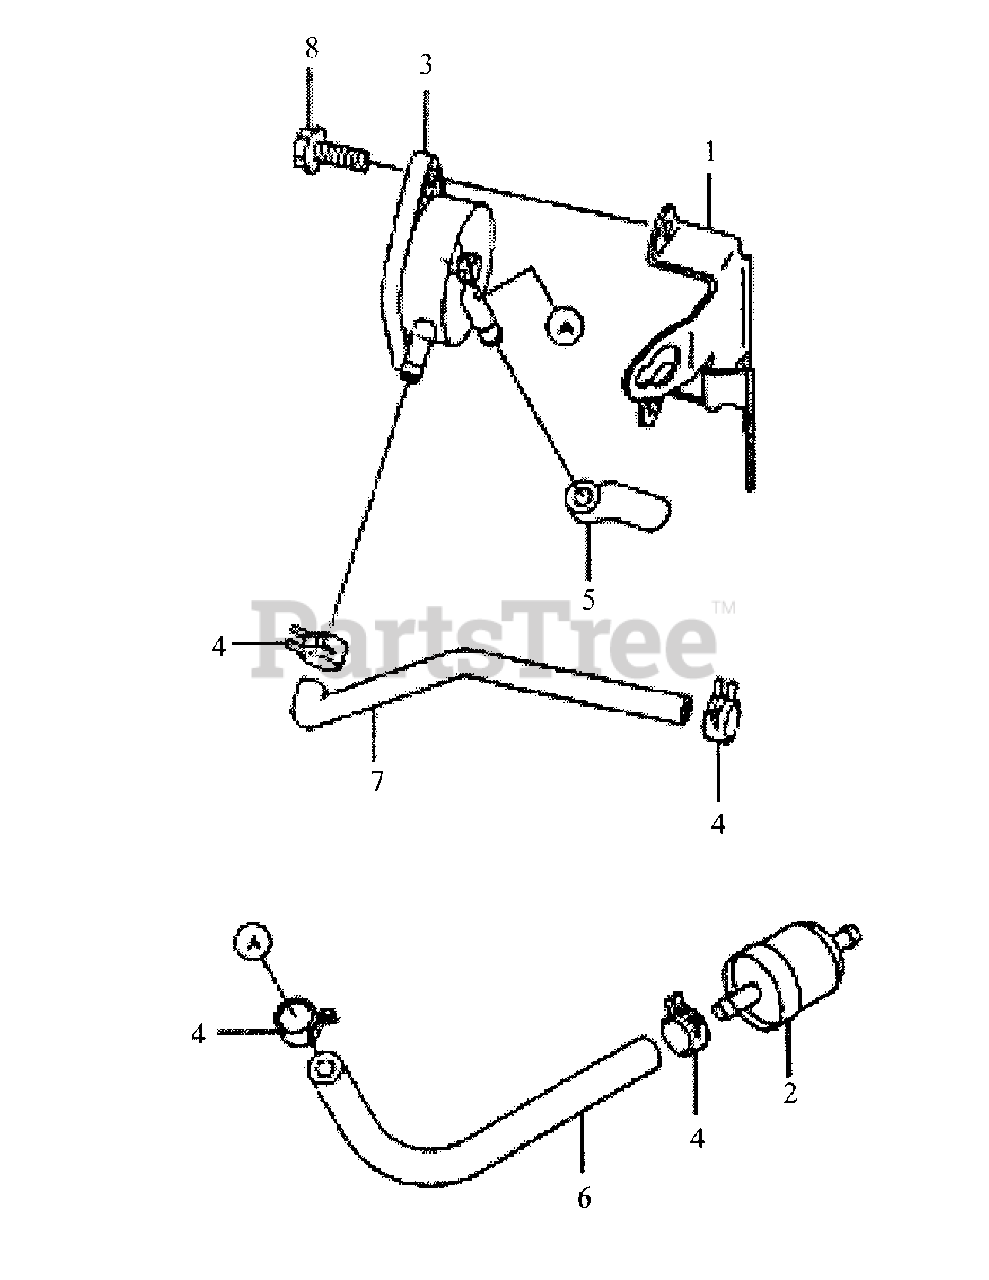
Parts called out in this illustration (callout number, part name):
2	Filter, Fuel
3	Pump, Full
4	Clamp
6	Tube 6.35x12.7x160
8	Bolt, Flange
